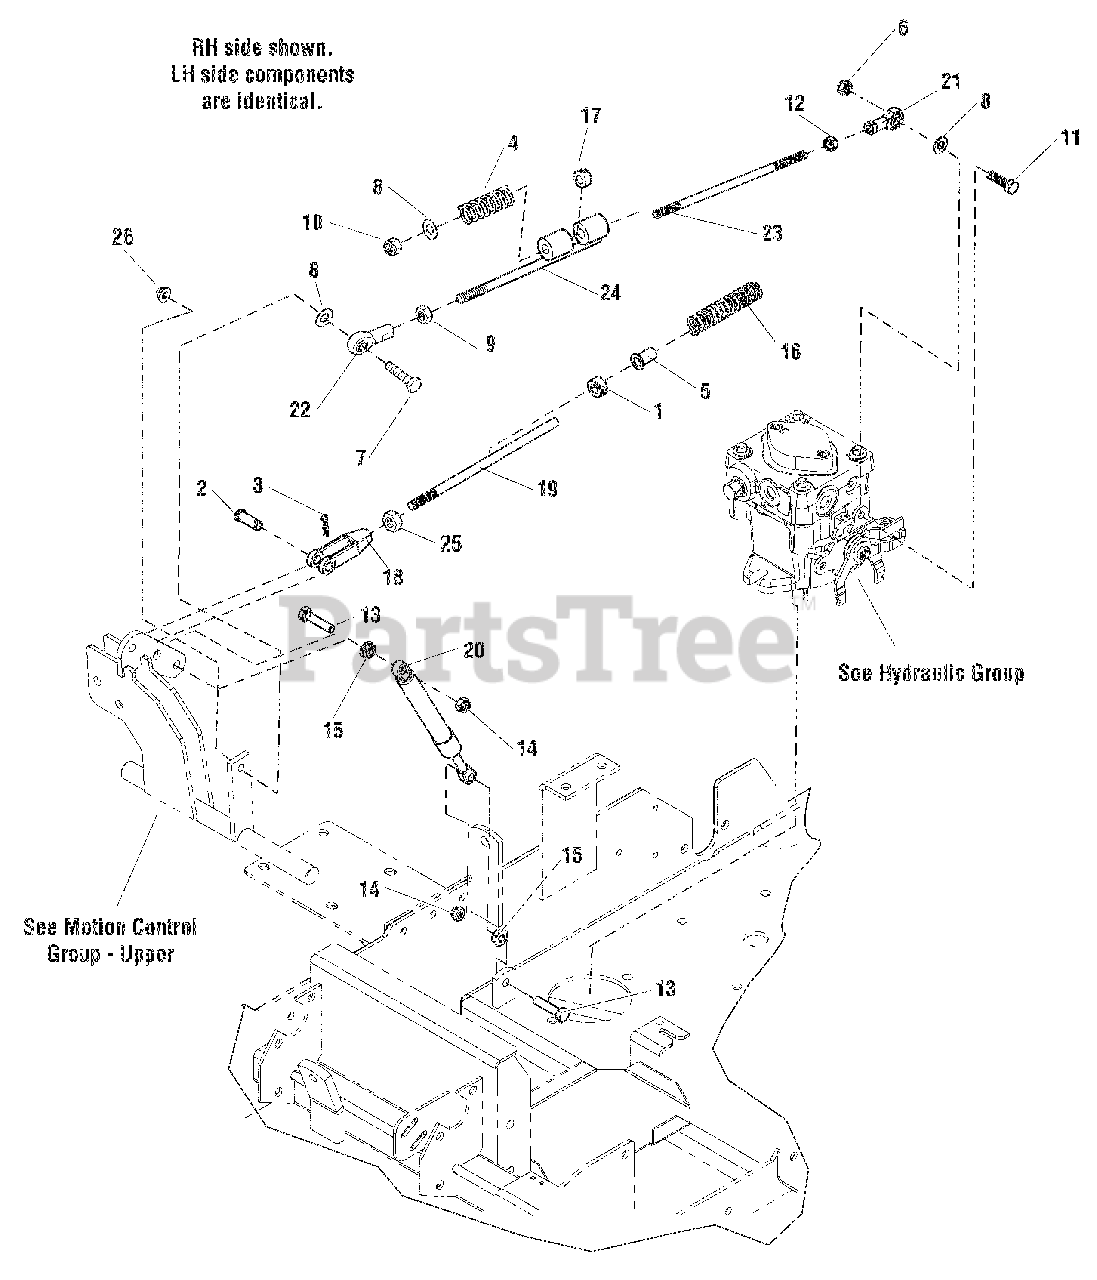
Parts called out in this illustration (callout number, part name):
1	COLLAR, 3/8 SET
2	PIN, CLEVIS, 3/8 X 1-1/8
3	PIN, HAIR, .0585 X 1-1/8, 1/4 EYE, YZ
4	SPRING, COMP, .496ID X 3.00LG X .112WR
5	BUSHING, NYLON
6	NUT, 5/16-18 HEX NYLON LOCK
7	BOLT, 5/16-18 X 1-1/4 GD5 YZ
8	WASHER, 5/16" SAE
9	NUT, 5/16-24 HEX
10	NUT, 5/16-24 HEX NYLON LOCK
11	BOLT, 5/16-18 X 1 GD5 YZ
12	NUT, 5/16-24 HEX, LH
13	BOLT, M8-1.25 X 35MM, GD8.8
14	NUT, M8-1.25 NYLON LOCK, CZ
15	NUT, M8-1.25 SERR. FLANGE, CZ
16	SPRING, REVERSE RETURN
17	COLLAR, 5/16 SET
18	CLEVIS, 3/8-24, PLASTIC
19	ROD, NEUTRAL CONTROL, 8
20	DAMPENER, CONTROL
21	BALL JOINT 5/16-24 LH FEMALE STAMPED STL
22	BALL JOINT 5/16-24 RH FEMALE STAMPED STL
23	ROD, 5/16 X 8.38, LH-RH, CZ
24	WELD, CONTROL ROD SLIDING
25	NUT, 3/8-24 HEX
26	NUT, 5/16-18 HEX NYLOCK FLANGE
